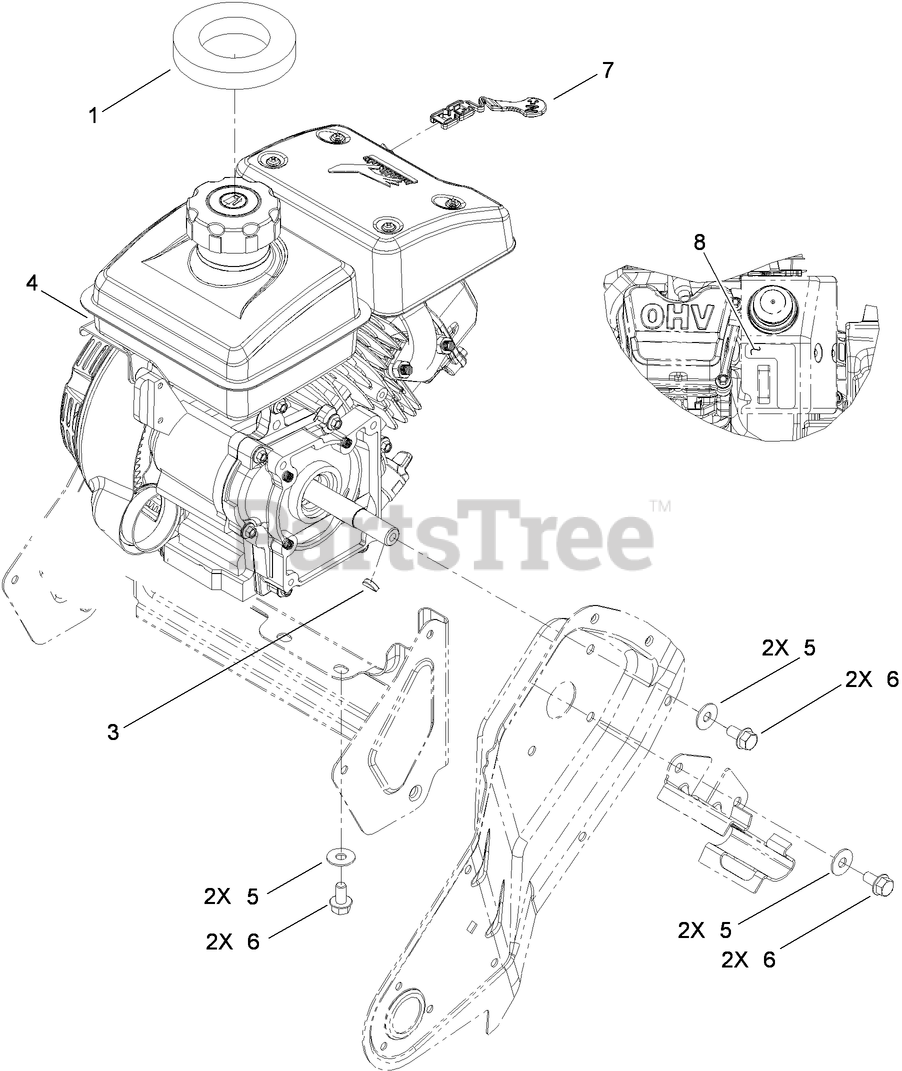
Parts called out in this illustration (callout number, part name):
1	SEAL-TANK
3	KEY-WOODRUFF
4	ENGINE-154
5	WASHER-BELLEVILLE
6	SCREW-HHF
7	LEVER-CHOKE
8	DECAL-CONTROL, ENGINE
